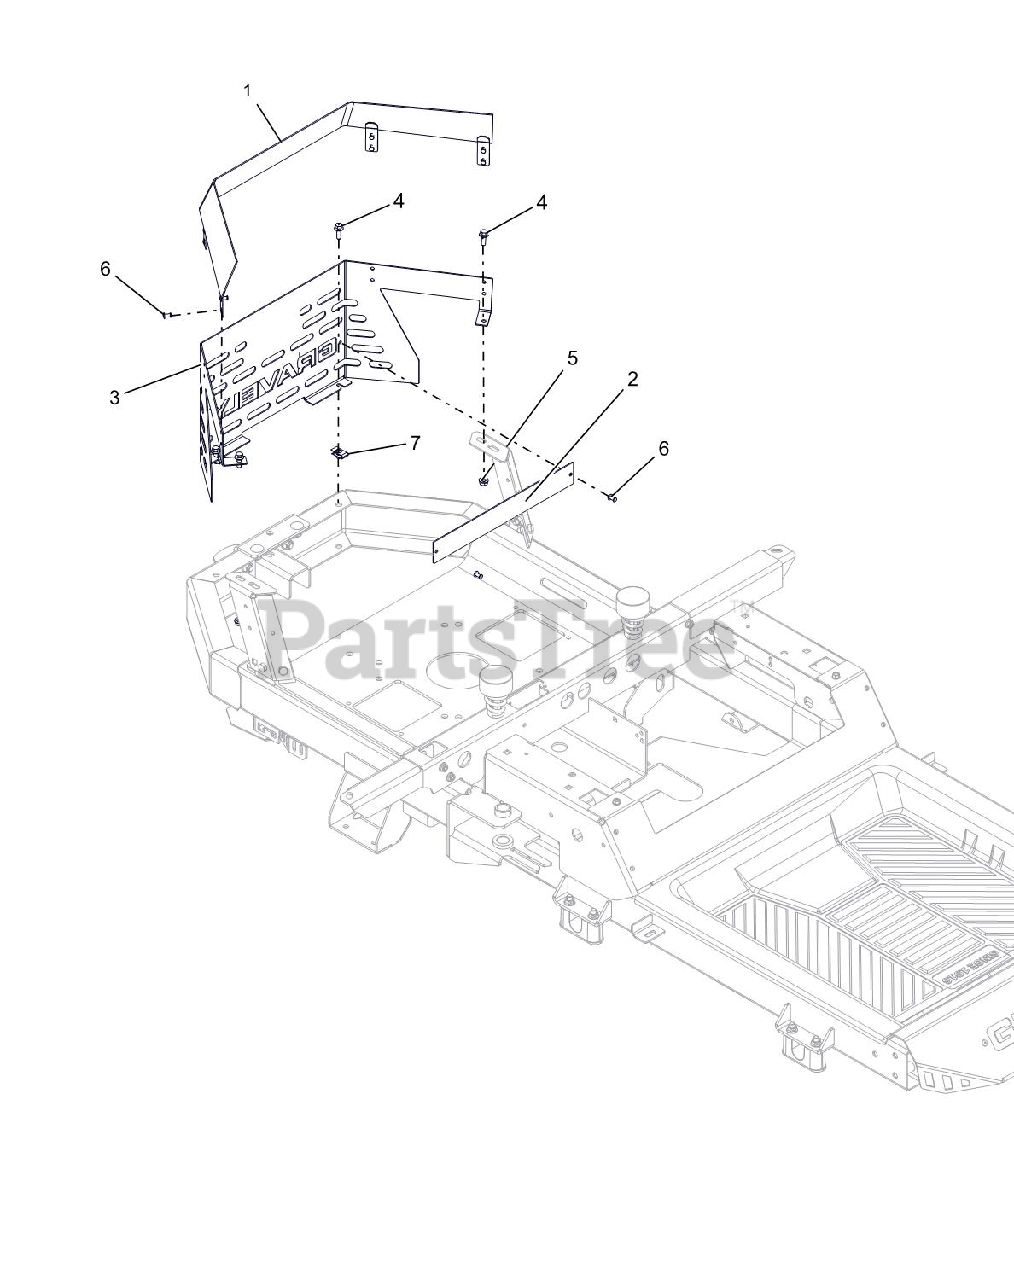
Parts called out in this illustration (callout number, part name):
1	BRACKET, ENGINE SHROUD TRIM
2	PLATE, SHROUD BACKER
3	SHROUD, ENGINE GRAVELY
4	BLT,HEX-FLG .25-20X.75 G5 BFP
5	NUT-LK-TOP-FLG .25-20 YWZC
6	RIVET, #66 STEEL POP PD BLACK
7	NUT-RTNR .25-20X.56
